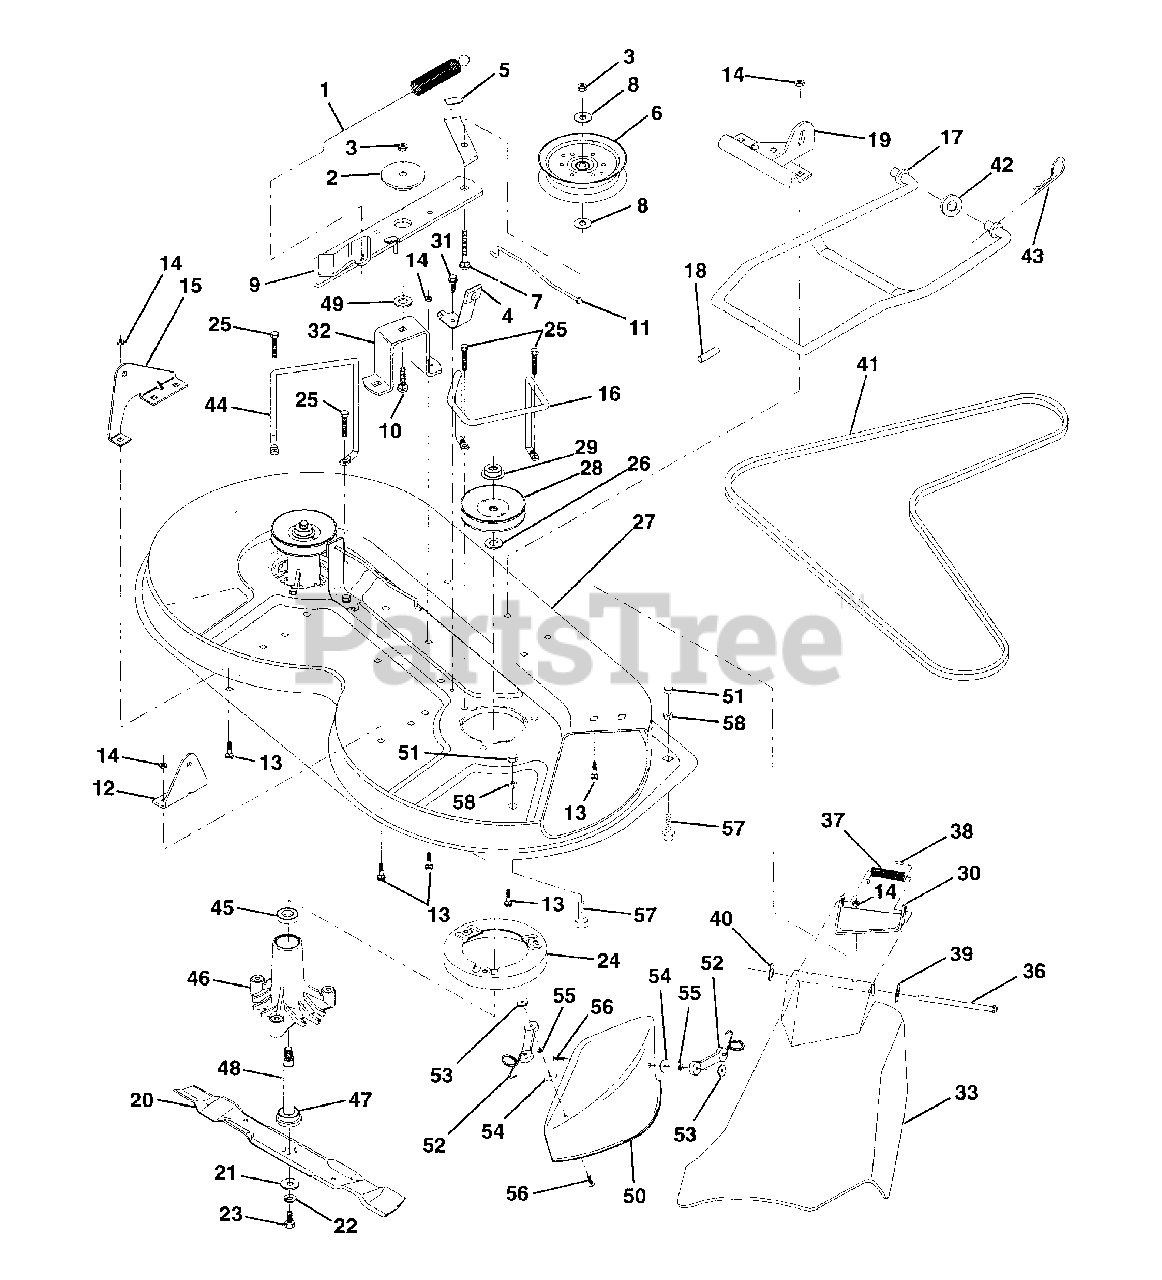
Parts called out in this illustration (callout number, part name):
1	Spring, Mower Clutch
2	Spacer, Retainer
3	Nut, Crownlock
4	Brake Asm.
5	Guide, Belt Idler
6	Pulley, Flat Idler
7	Bolt, Carr. 3/8-16 x 1-3/4 Gr. 5
8	Washer 13/21 x 7/8 x 10 Ga.
9	Arm Asm., Idler Mower
10	Bolt, Carriage 3/8-16 x 1-1/4
11	Rod, Brake
12	Bracket, Lift R. H. Rear
13	Bolt, Carriage 5/16-18 x 5/8
14	Nut, Crownlock 5/16-18
15	Bracket, Lift L. H. Rear
16	Keeper, R. H.
17	Link, Asm. Mower Stabilizer
18	Pin, Drive
19	Bracket, Asm. Front
20	Blade Mulching
21	Washer, Hard
22	Washer, Lock 3/8
23	Bolt 3/8-24 x 1-1/4 Gr. 8
24	Stripper
25	Screw Thdrol Hex Hd
26	Washer .150 Thk.
27	Deck Assembly
28	Pulley, Mandrel
29	Nut, Flangelock 9/16
30	Bracket, Asm. Deflector
31	Screw, Hex Wsh. Thdrol. 5/16-18 x 1 /2
32	Arm, Support Idler Mower
33	Deflector
36	Rod, Hinge
37	Spring, Torsion Deflector
38	Cap, Sleeve
39	Washer 11/32 x 5/8 x 16 Ga.
42	Washer 11/32 x 5/8 16. Ga.
43	Retainer, Spring
44	Keeper, L.H.
46	Housing Mandrel Vented
48	Shaft, Mandrel
49	Washer Wear 16 Ga.
50	Mulcher Plate
51	Acorn Nut 5/16-18
52	Latch Hook
53	Nut, Weld
54	Washer #10
55	Washer, Lock #10
56	Screw
57	Bolt, Hex 5/16-18 x 1
58	Locknut 5/16-18
